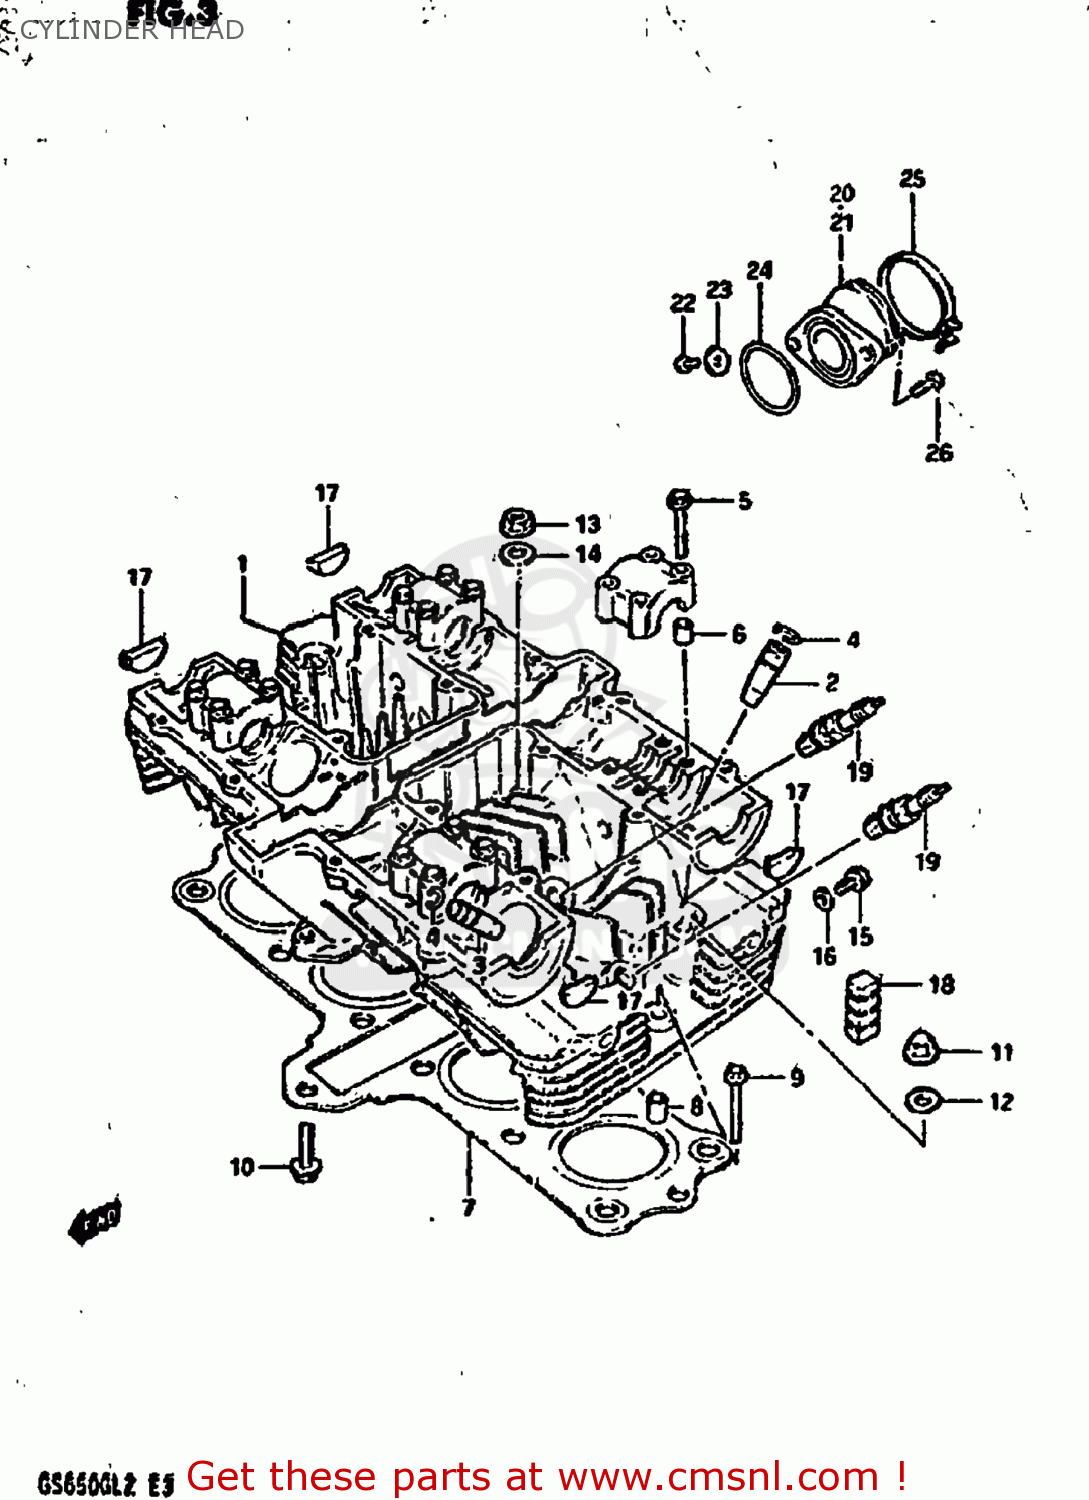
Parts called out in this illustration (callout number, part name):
1	HEAD,CYLINDER
2	GUIDE,INTAKE VALVE
3	GUIDE,EXHAUST VALVE
4	RING,SNAP
5	BOLT(6X39)
6	PIN(6.2X8X11)
7	GASKET,CYLINDER HEAD (MCA)
8	PIN
9	BOLT,UNDER
10	BOLT
11	NUT
12	GASKET (NAS)
13	NUT
14	WASHER(8.5X19X2.3)
15	BOLT
16	GASKET (NAS)
17	PLUG
18	PAD,CYLINDER
19	SPARK PLUG D8EA
20	PIPE,INTAKE,R
21	PIPE,INTAKE,L
22	BOLT
23	WASHER
24	O-RING
25	CLAMP
26	SCREW
